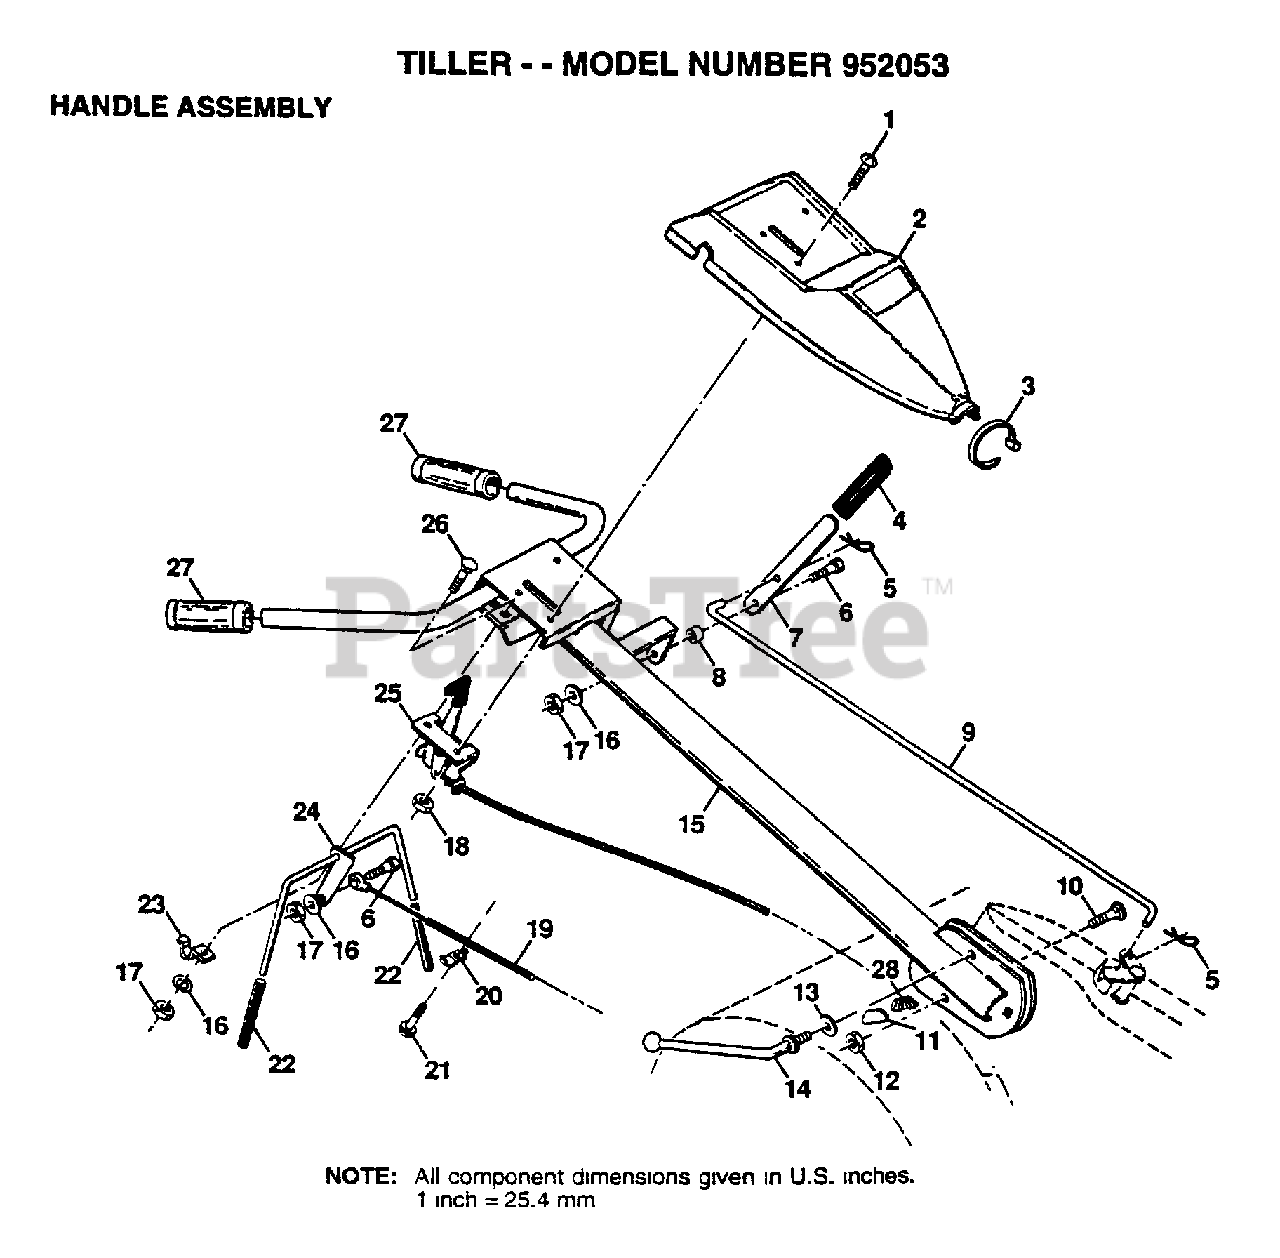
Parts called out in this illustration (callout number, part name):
1	SCREW.PNHD.10-24
2	"PANEL,CONT TI"
3	TIE CABLE CRT
4	GRIP T
5	RETAINER M
6	SHOULDER BOLT ST
7	SHIFT HANDLE CRT
8	GROMMET CRT
9	ROD.SHIFT
10	BOLT D
11	LOCK CRT
12	LOCKNUT
13	WASHER CRT
14	LEVER LOCK CRT
16	LOCKWASHER
19	CABLE-CLUTCH CRT
20	CONDIUT CLIP T
22	GRIP BAR CRT
24	"ASSY CONTROL, BAR"
25	CONTROL.THROTTLE
26	BOLT
27	GRIP NUB SNGL HDL
28	LOCK.HANDLE
